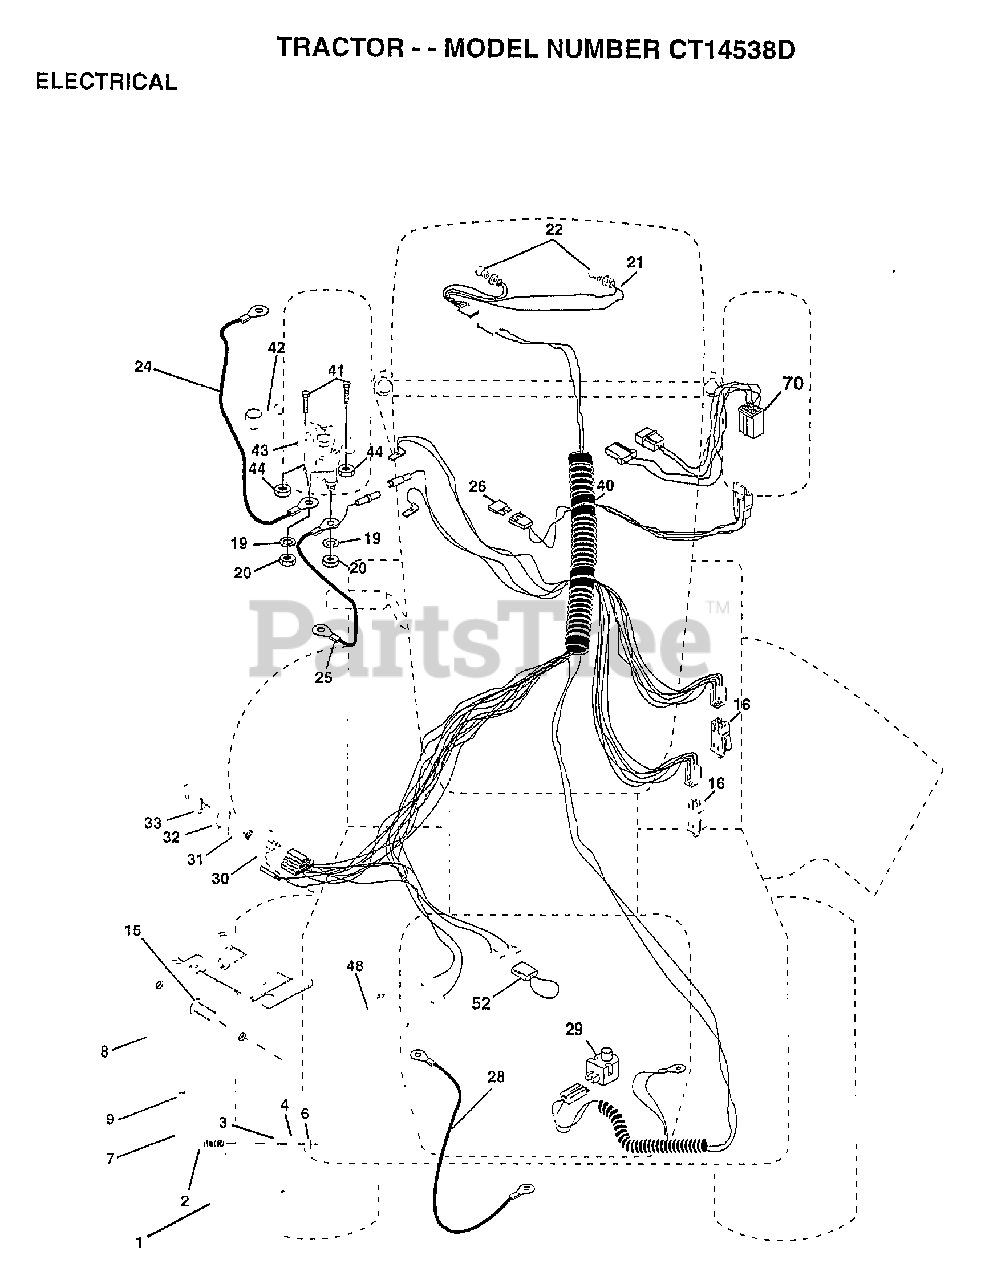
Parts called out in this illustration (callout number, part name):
2	BOLT LT
3	WASHER
4	LOCKWASHER
7	TUBE T
8	"CASE,BATTERY.MECH"
9	HOSE CLAMP T
15	FASTNER.SNAP-IN
16	SWITCH INTERLOCK
20	NUT
21	"HARNESS,LIGHT SOC"
22	HEADLAMP BULB
24	"CABLE T, BATTERY"
25	CABLE.BTRY.6GA.RD
26	FUSE HYT
28	CABLE T
29	SWITCH SEAT
30	SWITCH IGN 4POS
31	NUT IGNITION
32	COVER KEY SWITCH
33	KEY
40	HARNESS-IGNITION
41	BOLT HXHD FIN
44	NUT HXKEP 1/4X20
48	ADAPTER AMMETER
52	PROTECTION LOOP
70	HARNESS.ENG.DUAL
